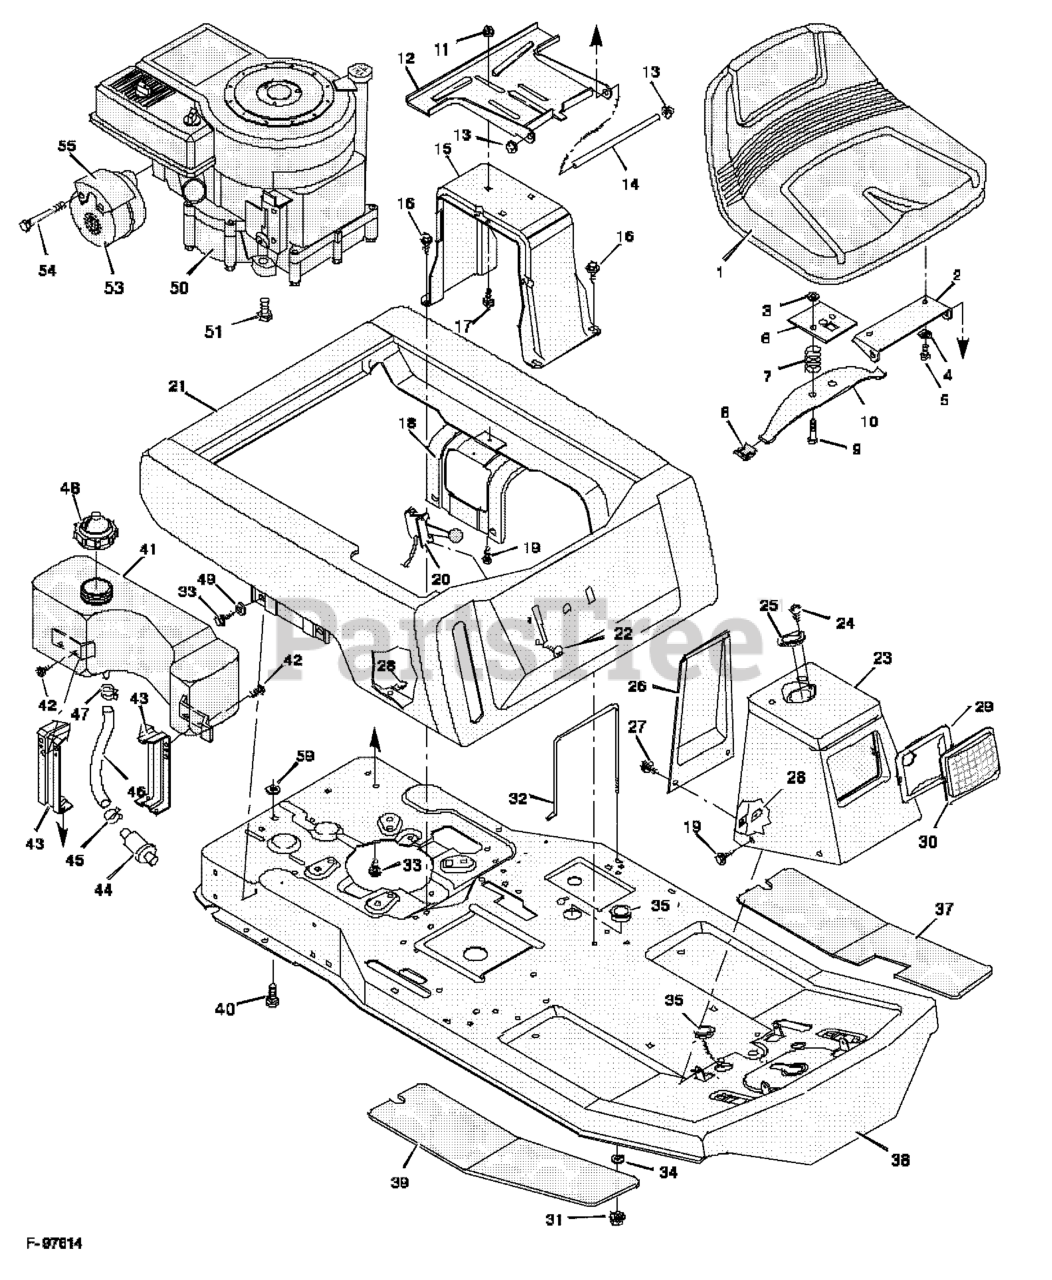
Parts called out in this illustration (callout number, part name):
2	Hinge, Seat
3	Retainer
4	Lockwasher
5	Bolt, Hex
6	Plate, Seat Switch
7	Spring, Compression
8	Gilde, Seat Spring
9	Bolt, Shoulder
10	Spring, Seat
11	Locknut, Flange
12	Bracket, Seat Pivot
13	Cap, Push On
14	Rod, Seat Hinge
15	Support, Seat
17	Bolt, Carriage
18	Support, Body
20	Throttle Control
23	Console Assembly
26	Console, Plate
29	Reflector
31	Locknut
32	Clamp, Battery
35	Grommet
36	Mat, Left
38	Frame, Assembly
39	Mat, Right
40	Bolt, Carriage
41	Tank, Fuel
43	Bracket, Fuel Tank
44	Filter, Fuel
46	Line, Fuel
47	Clamp
48	Cap, Fuel
49	Washer
50	Engine *
51	Bolt, Engine Mount
53	Muffler
55	Shield, Heat
59	Washer
